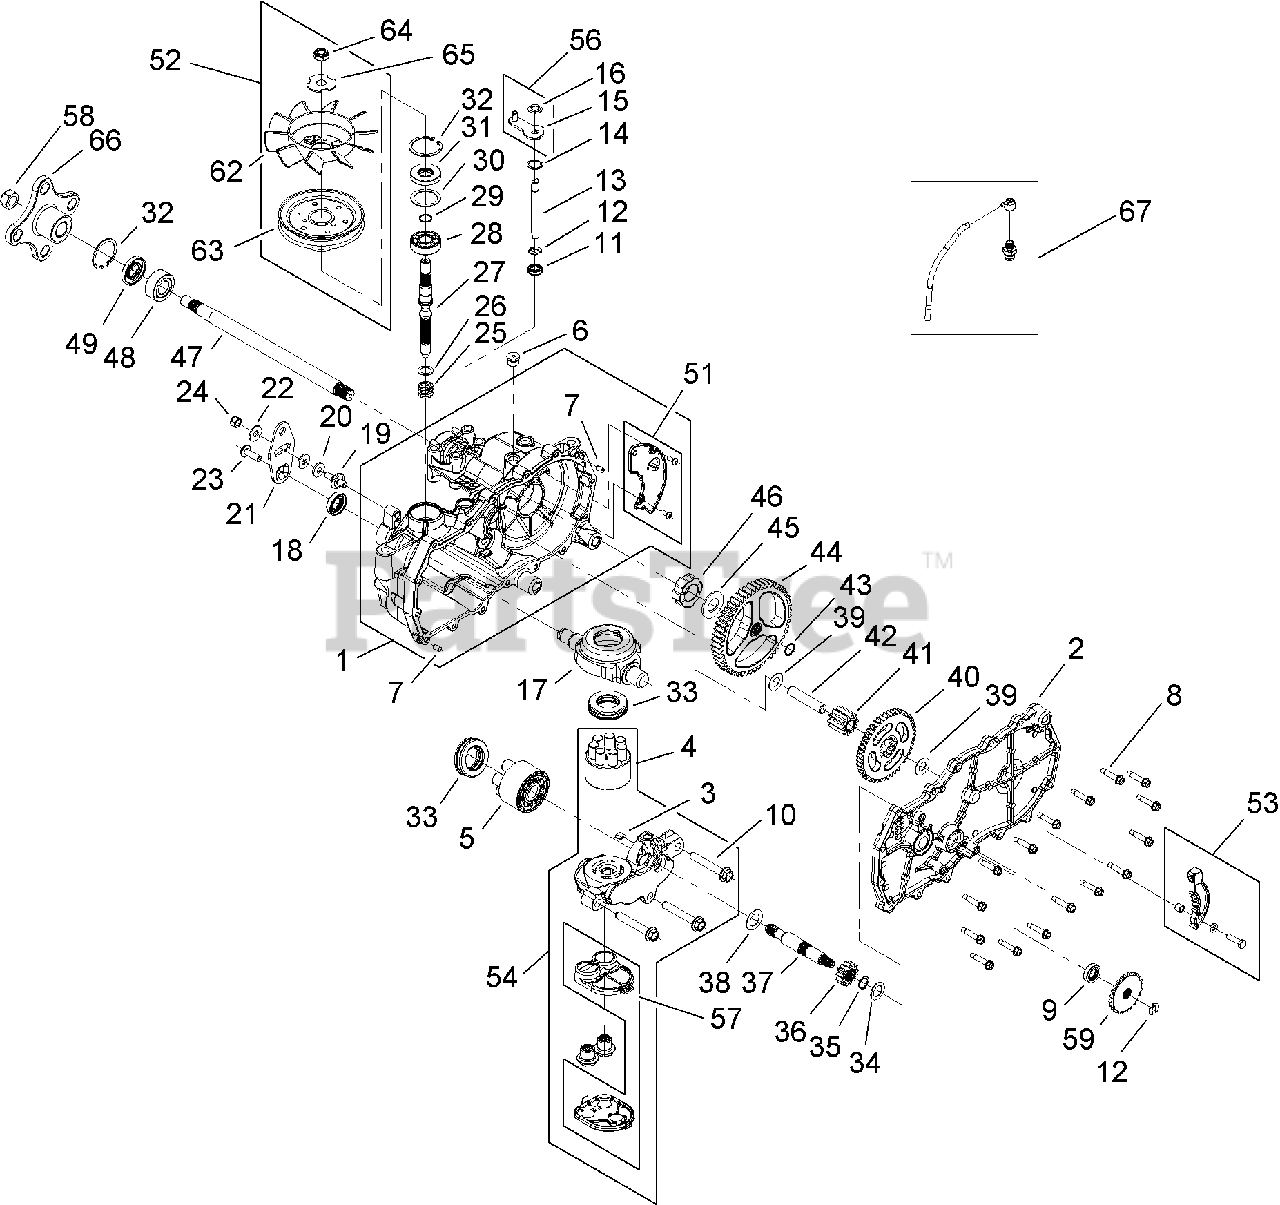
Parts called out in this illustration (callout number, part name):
1	LH MAIN HOUSING ASM
2	LH SIDE ASM
3	PLATE-BYPASS
4	PUMP BLOCK ASM
5	CYLINDER BLOCK KIT
6	PLUG-THREAD, STRAIGHT
8	SCREW-HHF
9	BRAKE SEAL KIT
11	SEAL-LIP
12	RING-RETAINING, EXT
13	ROD-BYPASS
14	RING-RETAINING, INT
15	ARM-BYPASS
16	RING-RETAINING, EXT
17	SWASHPLATE-TRUNNION
20	PUCK-FRICTION
21	ARM-CONTROL
22	WASHER-PIVOT
25	SPRING-BLOCK
26	WASHER-THRUST, BLOCK
27	SHAFT-INPUT
28	BEARING-BALL
29	RING-RETAINING
32	RING-RETAINING
33	BEARING-THRUST
34	WASHER-FLAT
35	RING-RETAINING
36	GEAR-PINNION, 13T
37	SHAFT-MOTOR
38	WASHER-SHAFT, MOTOR
41	GEAR-JACKSHAFT, 10T
42	PIN-JACKSHAFT
43	RING-SPIRAL, RETAINING
44	GEAR-52T, BULL
46	BEARING-SLEEVE
47	SHAFT-AXLE
48	BUSHING-AXLE
51	LH EXPANSION PLATE KIT
52	FAN PULLEY KIT
53	BRAKE ARM KIT
54	LH CENTER SECTION FILTER KIT
56	BYPASS ARM KIT
57	FILTER KIT
59	DISC-BRAKE, COG
62	FAN
63	PULLEY
67	BREATHER KIT
